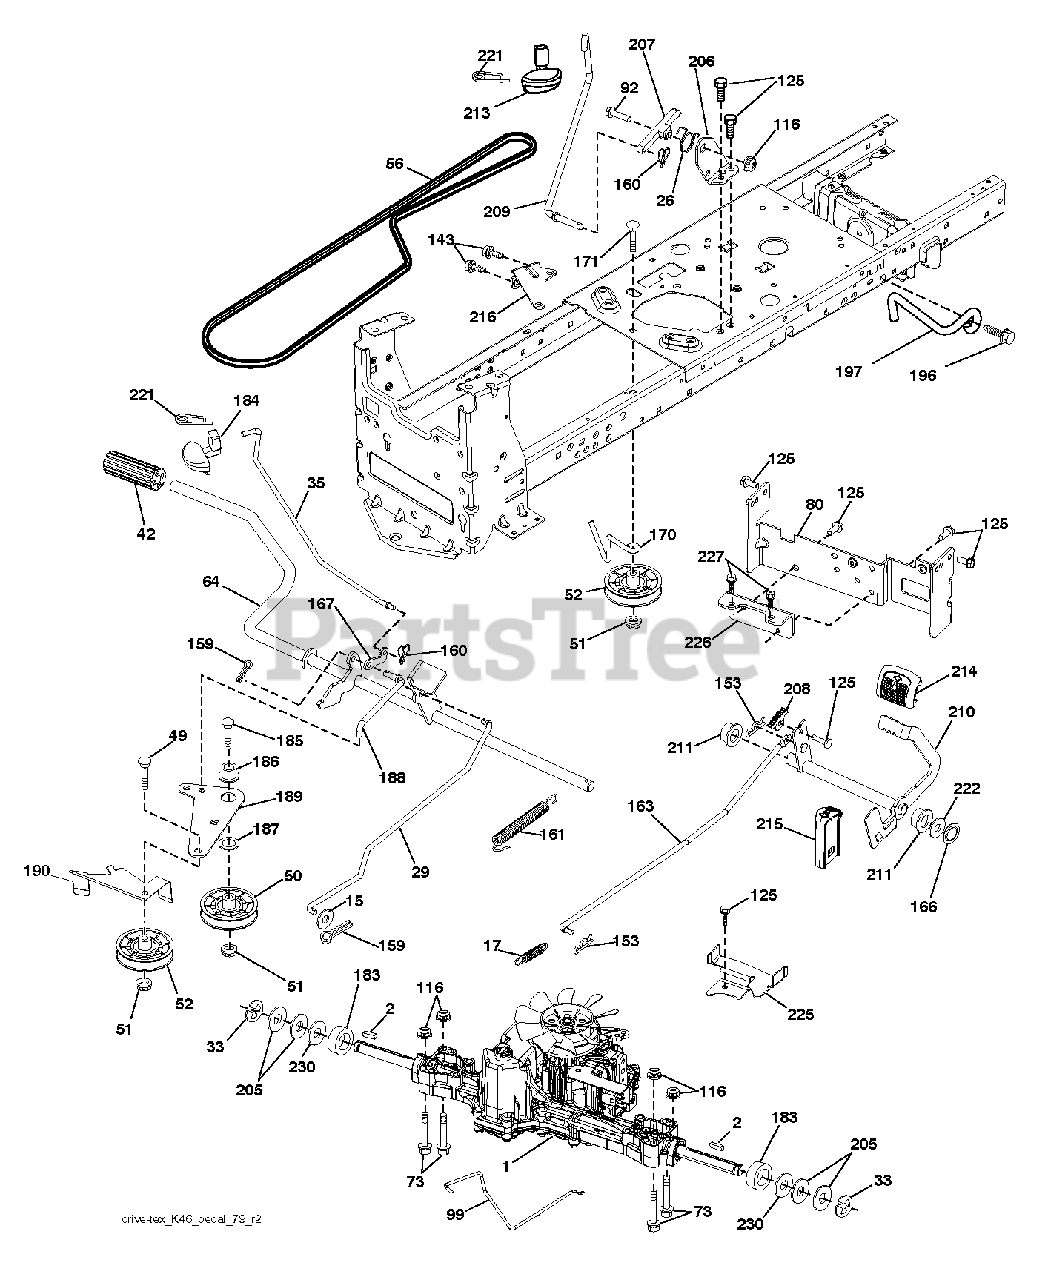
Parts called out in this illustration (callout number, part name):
2	SQUARE KEY
15	WASHER
17	SPRING.BRAKE.K46.GREEN
26	SPRING.RETURN.CRUISE
29	ROD.BRAKE.K46
35	ROD.BRAKE.PARTK.HUSQ.TEX
42	PEDAL COVER T
50	IDLER.FLAT.910.OFFSET
51	NUT LOCK FLG 3/8-16 UNC
52	IDLER.V-GROOVE.910.OFFSET
56	V-BELT.MOWER.92.40.42/K46
64	SHAFT.ASM.PEDAL.BRK.CNTR
80	STRAP.TORQUE.K46.K57R.TT
92	BOLT
99	ROD.SPRING.BYPASS.K46.LT.Z
116	NUT LOCK HEX FLANGE 5/16-18
125	SCREW
143	SCREW LT
153	RETAINER M
159	COTTER PIN
160	RETAINER CLIP
161	SPRING, RETURN LT
163	ROD.CONTROL.K57R.K46
166	NUT.PUSH.625
167	LATCH.BRAKE.SPRING
170	KEEPER.V-IDLER.CENTER.
183	SPACER AXLE
184	RB HANDLE.PARKG.BRK.HUS/PRED
186	SPACER.RETAINER
187	WASHER 12/32X2X10GA
188	RP LINK.CLUTCH.GROUND.DRIVE
189	BELLCRANK.GROUND.DRIVE.TEX.
190	KEEPER.BELLCRANK.DRIVE
196	SCREW 3/8-16X1
197	LINK.CLUTCH.ANIT-ROTAT
206	BRKT.MOUNT.LATCH.CRUIS
207	LATCH.CONTROL.CRUISE
208	GEAR.SECTOR.CONTROL.CR
209	ROD.CONTROL.CRUISE.GT.
210	ROCKER.ASM.PEDAL.CONTR
211	BEARING.NYLON
213	KNOB.CONTROL.CRUSIE.HU
214	PEDAL.FORWARD.PAD.TEX
215	PEDAL.REVERSE.TEX.GT.4
216	BRACKET.PULLEY.IDLER.W/TEX
221	RETAINER.SPRING.CLIP.H
222	WASHER 21/32 X 1-1/4 X 10 GA.
225	KEEPER.BELT.TRANSAXLE.K46
226	BRACKET.MOUNT.TORQUE.K46.TLT
227	SCREW
230	WASHER.HARDENED
